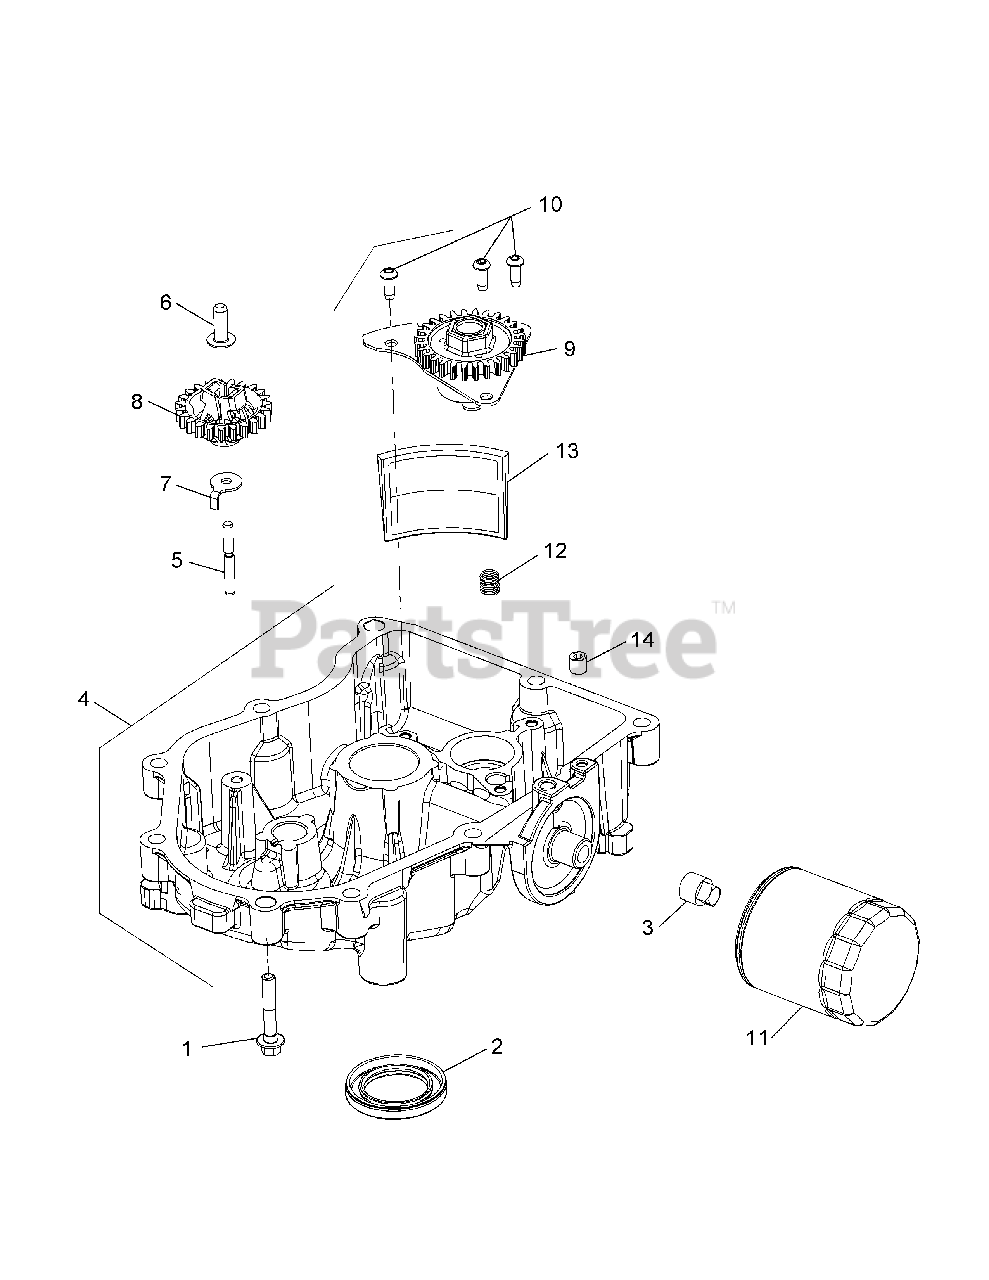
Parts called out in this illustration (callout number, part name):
1	Flange Screw, M8 x 1.25 x .45
3	Pipe Plug, 3/8
4	Oil Pan Assembly
5	Governor Gear Shaft
6	Governor Regulating Pin
8	Governor Gear Kit
9	Oil Pump Assembly
10	Button Head Screw
12	Compression Spring
14	Pipe Plug, 1/8
